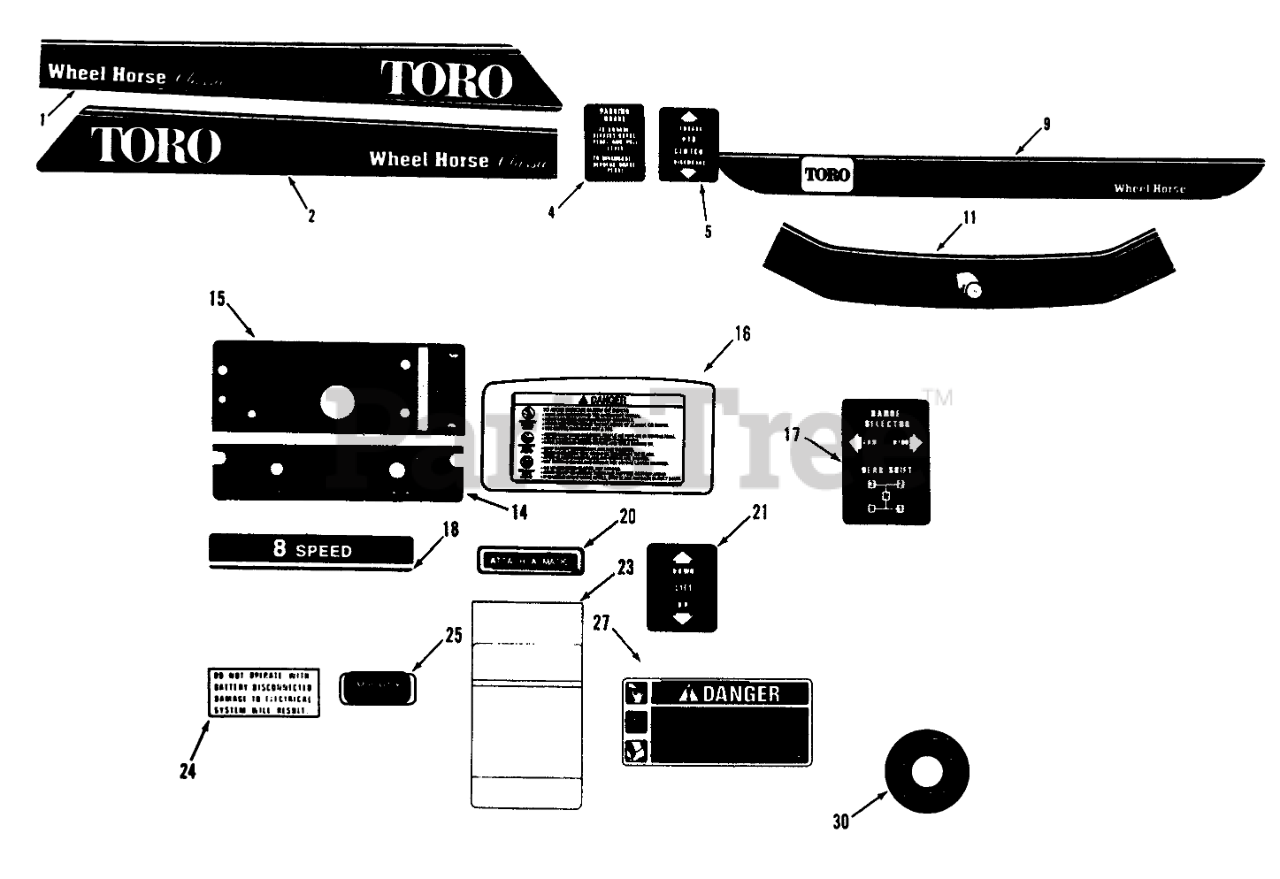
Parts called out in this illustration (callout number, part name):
1	DECAL-HOOD CLASSIC
2	DECAL-HOOD CLASSIC
4	DECAL-PARKING, BRAKE
5	DECAL PTO CLUTCH
9	DECAL-FENDER
11	DECAL-FRONT HOOD
14	Decal-Switch Plate
15	DECAL-LOWER DASH
16	Decal-Danger
17	DECAL-SHIFT PATTERN
18	DECAL-312 8-SPEED
20	Decal-Attac-O-Matic
21	DECAL-LIFT
23	Decal-Maintenance
24	DECAL ELECT SYSTEM
25	Decal-Unidrive
27	DECAL-DANGER
30	Decal-Air Cleaner
